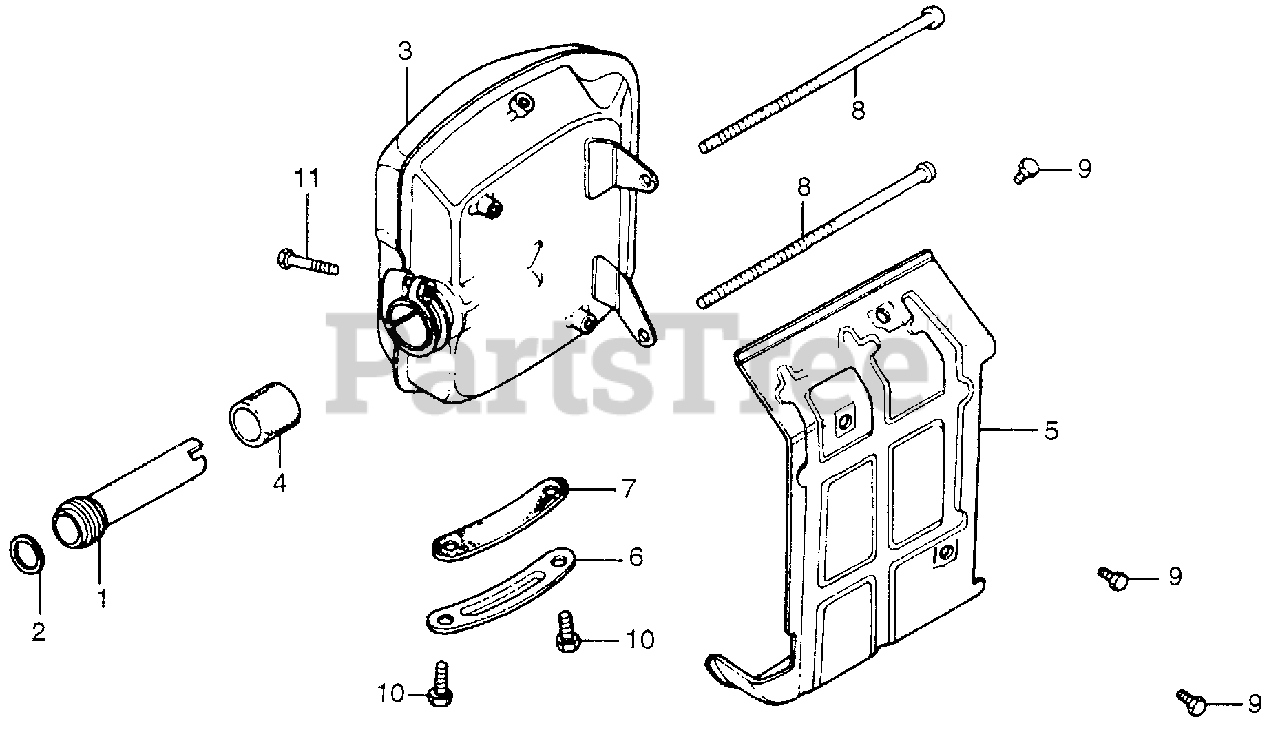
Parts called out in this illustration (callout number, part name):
1	PIPE, EX. (NOT AVAILABLE)
2	GASKET, EX. PIPE (NOT AVAILABLE)
4	SEAL, EX. PIPE (NOT AVAILABLE)
5	PROTECTOR, MUFFLER (NOT AVAILABLE)
6	LID, MUFFLER
7	GASKET, MUFFLER
8	BOLT, ALTERNATOR SET (NOT AVAILABLE)
9	BOLT, HEX. (5X8)
10	BOLT, HEX. (6X14)
11	BOLT, HEX. (6X32)
